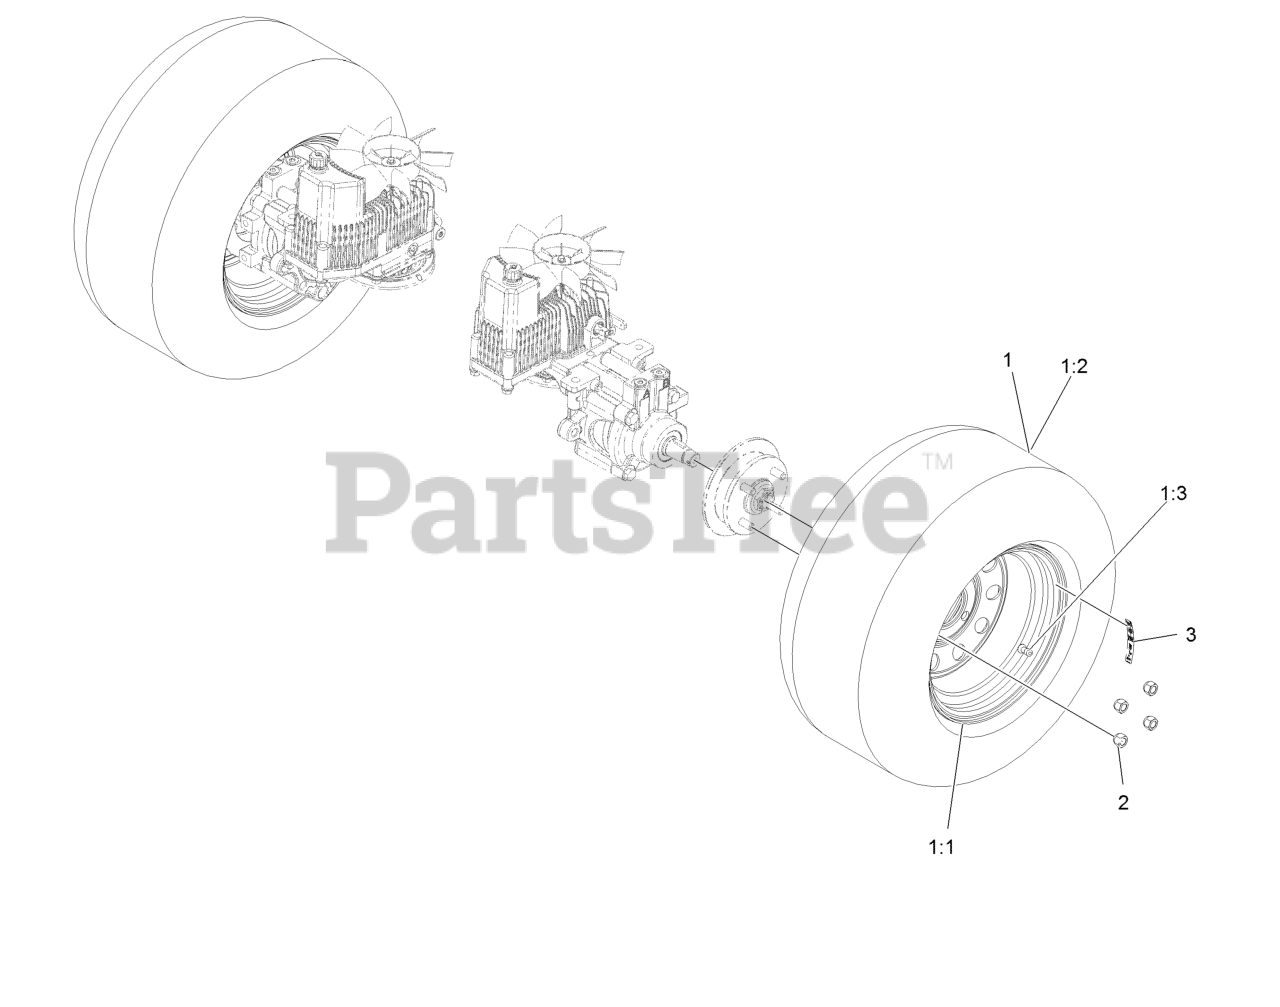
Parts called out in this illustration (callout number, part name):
1	Wheel And Tire ASM
1:3	Stem-Valve
2	Nut-Lug 1/2-20
3	Decal-Torque, Wheel Hub Lug
